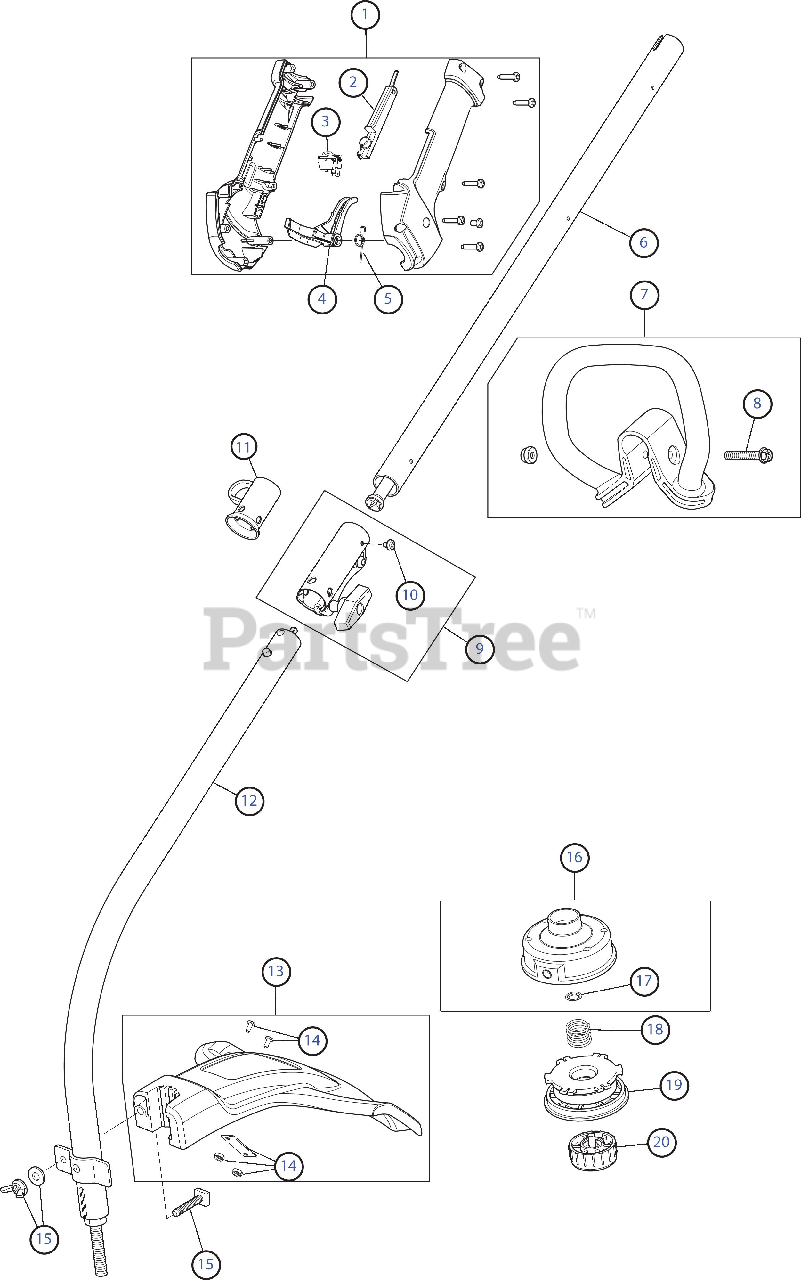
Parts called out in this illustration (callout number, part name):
1	Throttle Housing Assembly
2	Throttle Trigger Lock-Out
3	Throttle Switch Assembly
4	Throttle Trigger
5	Throttle Trigger Spring
6	Upper Shaft Housing Assembly
7	D-Handle
8	D-Handle Hardware Assembly
9	Split Boom Coupler
10	Coupler Anti-Rotation Screw
11	Hanger
12	Lower Shaft Housing Assembly
13	Shield Assembly
14	Blade Assembly
15	Shield Mounting Hardware
16	Outer Spool Assembly
17	Retainer
19	Inner Reel
20	Bump Head Knob Assembly
